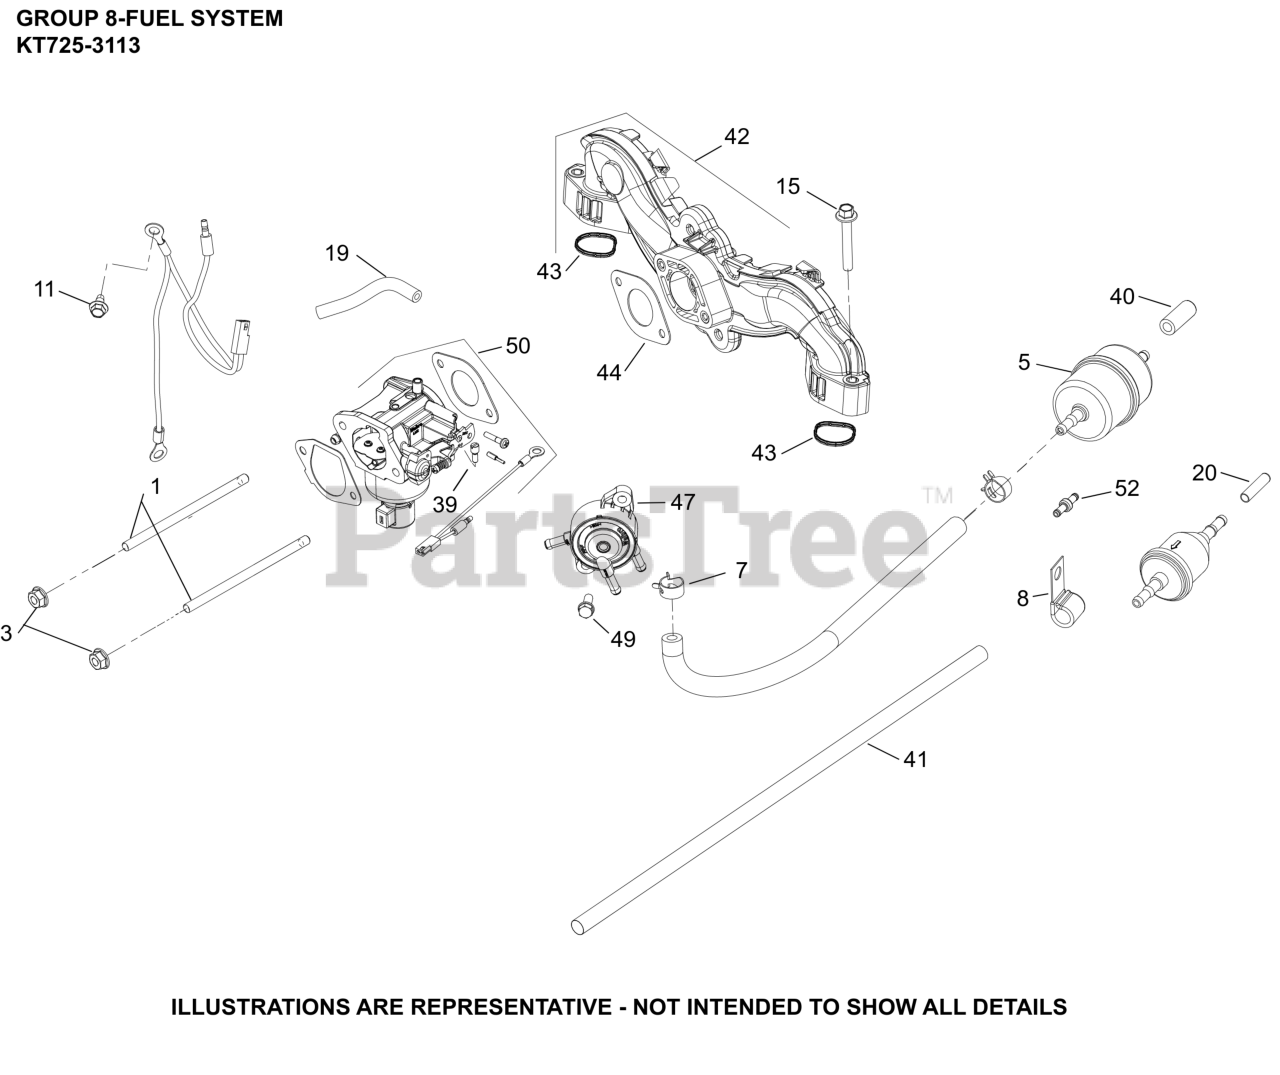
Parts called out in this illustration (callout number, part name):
3	NUT, FLG M6X1.0
5	FILTER, FUEL
7	SPRING CLAMP, HOSE
8	CLIP, CABLE (KM)
11	SCREW, THREAD FORMING
15	SCREW, FLG M6X1.0X40
19	HOSE, EVAPORATIVE 20"- (#24326143S)
20	CAP, MASKING
39	SCREW, THROTTLE STOP
40	MASKING CAP
41	SLEEVE, ANTI-ABRASION
42	INTAKE MANIFOLD W/GASKETS
43	O-RING, INTAKE PORT
44	GASKET, CARBURETOR (PIM, CV)
47	PUMP, FUEL (PULSE)
49	SCREW, HEX HEAD
50	KIT, CARBURETOR COMPLETE
52	FITTING, FUEL SYSTEM
NI	KIT,REPAIR OVERHAUL(WALBRO)
NI	KIT,BOWL O-RING(WALBRO)
NI	KIT, HIGH ALT (4000-8000 FT)WALBRO)
NI	KIT,SOLENOID REPAIR(WALBRO)
NI	KIT,REPAIR FLOAT(WALBRO)
